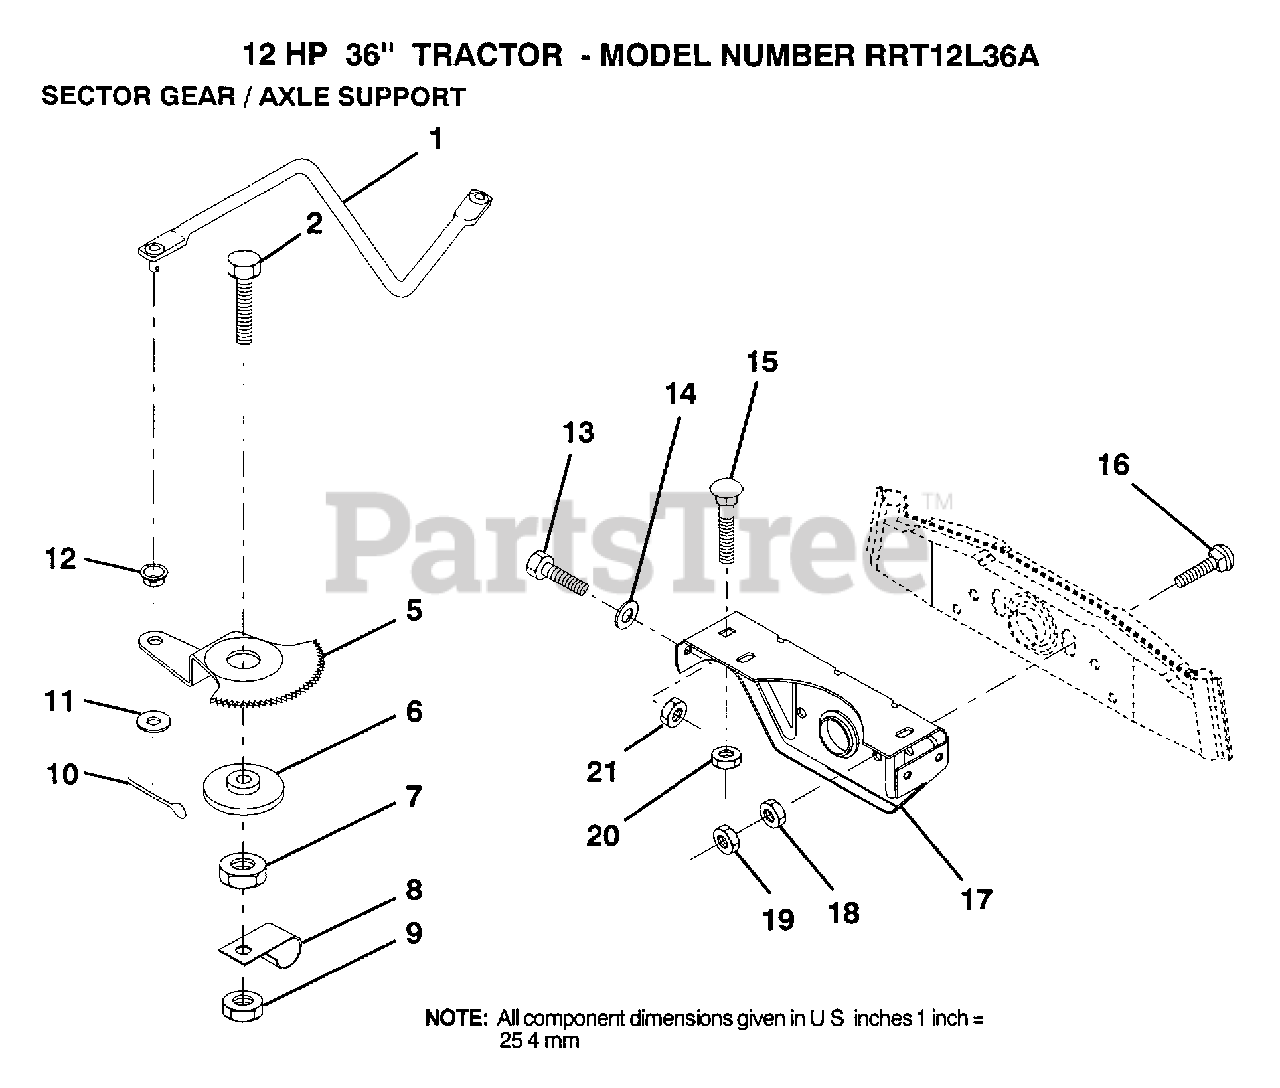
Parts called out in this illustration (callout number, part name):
1	DRAG LINK
2	"BOLT,HEX"
5	GEAR SECTOR
6	BUSHING
7	NUT
8	CLIP INSULATOR
9	NUT LTV
10	COTTER PIN
11	WASHER
12	BUSHING.DRAGLINK
13	BOLT
14	WASHER
15	BOLT
16	BOLT
17	"SUPT,FRT AXLE"
18	NUT.HEX.3/8-16UNC
19	LOCKNUT
